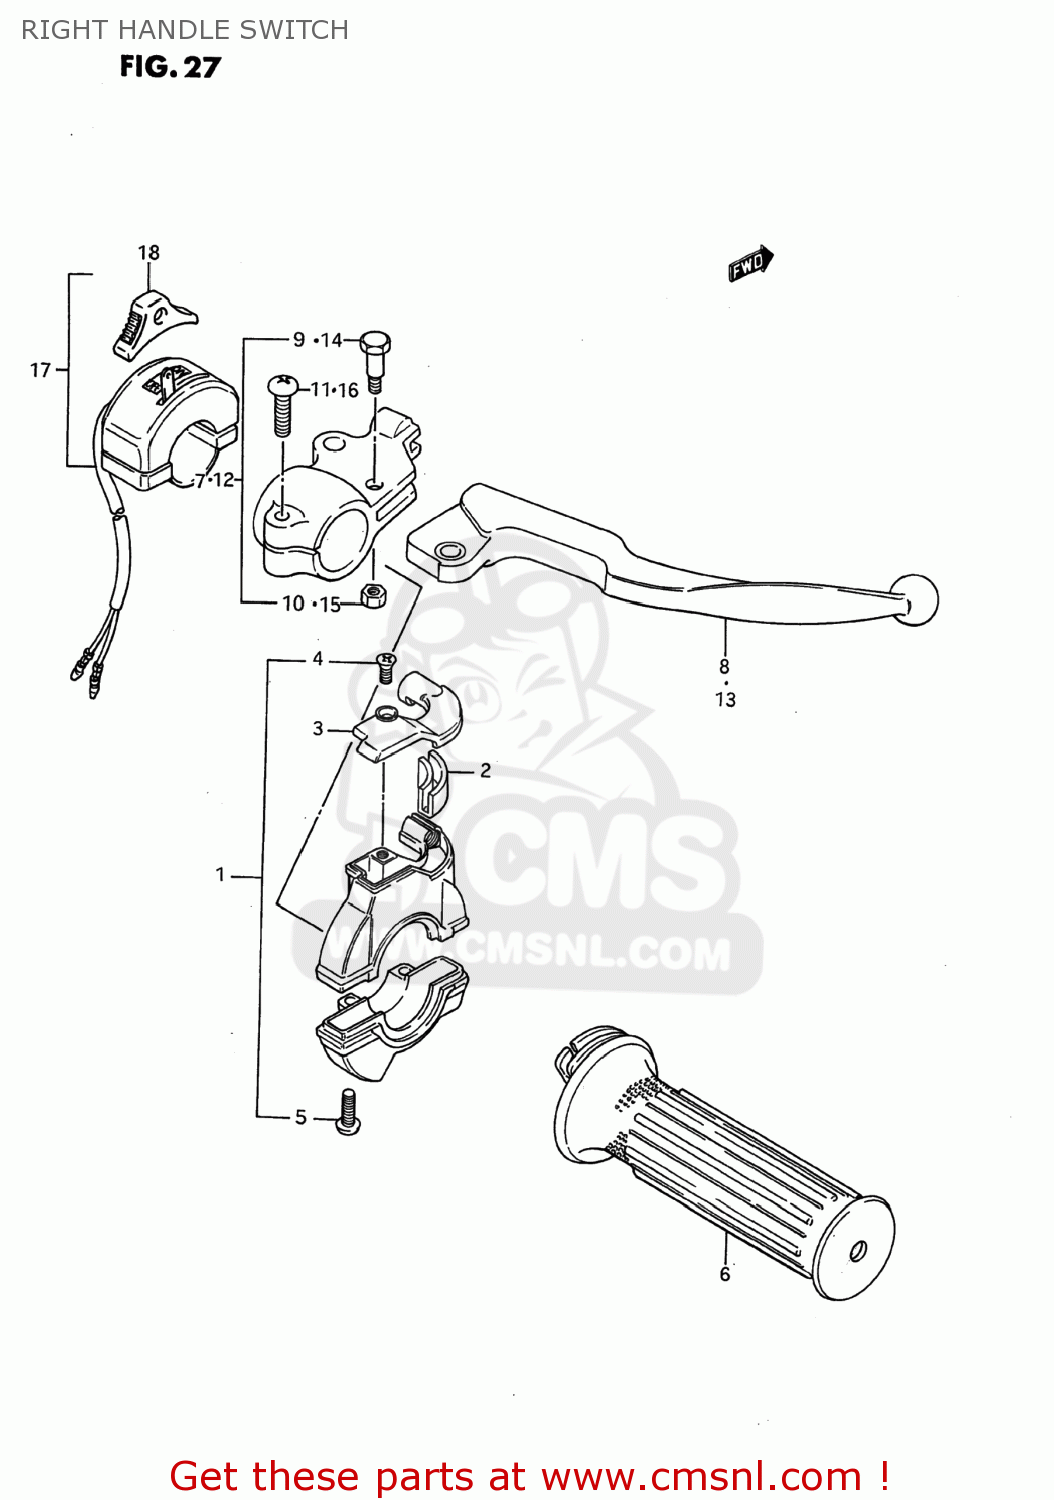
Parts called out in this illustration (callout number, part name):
1	CASE ASSY,THROTTLE
2	GUIDE PIECE,THROTTLE
3	COVER,THROTTLE CASE
4	SCREW,UPPER
5	SCREW
6	GRIP,THROTTLE
7	LEVER ASSY,BRAKE
8	LEVER,BRAKE
9	BOLT,LEVER PIVOT
10	NUT 5MM
11	SCREW
12	LEVER ASSY,BRAKE
13	LEVER,BRAKE
14	SCREW
15	NUT 8MM
16	SCREW
17	SWITCH ASSY,LIGHTING
18	KNOB,LIGHTING & DIMMER
